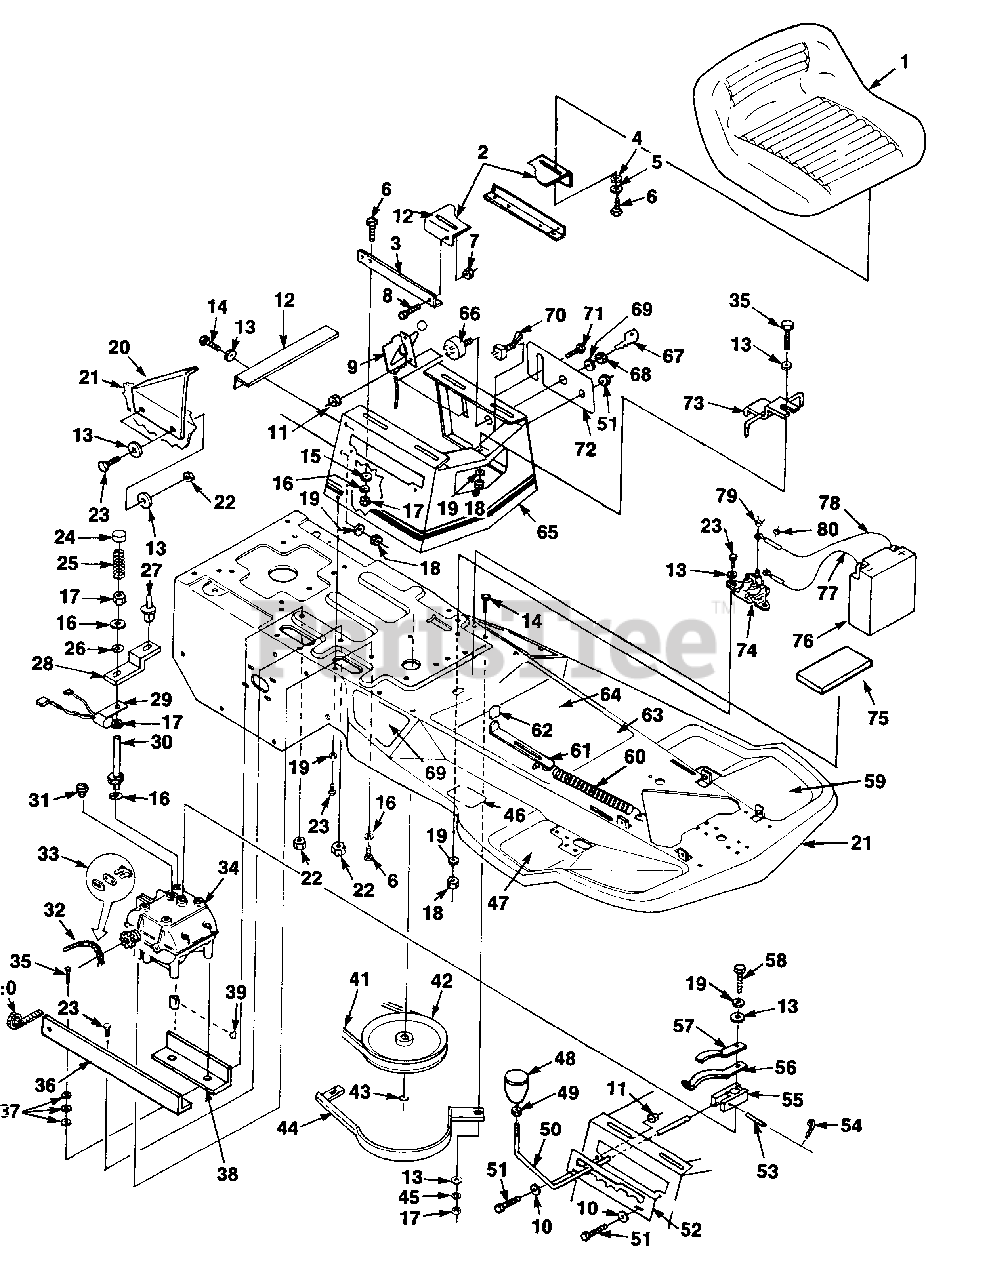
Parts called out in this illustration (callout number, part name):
2	BRACKET- Seat
3	SEAT RAIL
5	Superseded by UP03791
6	Superseded by UP03381
12	BRACKET- Reinforcement
13	Superseded by 84026
14	Superseded by 80052
15	Superseded by UP07173
16	Superseded by UP03407
17	Superseded by 81018
18	Superseded by JA993730
19	Superseded by UP03409
20	BRACKET- Chain guard
22	Nut - hex 1/4-20 lock
26	RETAINER- Spring
28	BRACKET- Transmission
29	NEUTRAL START (Safety Mod)
30	STUD- 5/16-18
34	TRANSMISSION- Peerless Tecumseh
35	Superseded by UP04158
36	ANGLE- Long
39	KEY (#9) 3/16 x 3/4
43	RING- Retaining
44	BELT GUIDE- Transmission
48	KNOB- Shift lever
49	NUT- Hex jam 3/8-24
51	SCREW 10-24 x 1/2
52	PLATE- Shift
55	BRACKET- Pivot
57	SPRING LEAF
58	SCREW- Hex hd 1/4-28 x 7/8
59	FOOT REST (left hand)
61	LATCHING- Parking brake
62	KNOB- Latch
65	SUPPORT- Seat
66	SWITCH- Ignition
70	Superseded by UP06659
71	SCREW- (10-24 x 1/2")
75	BATTERY PAD
77	BATTERY CABLE- Ground
79	NUT- (1/4-20)
80	NUT- Mach (8-32)
